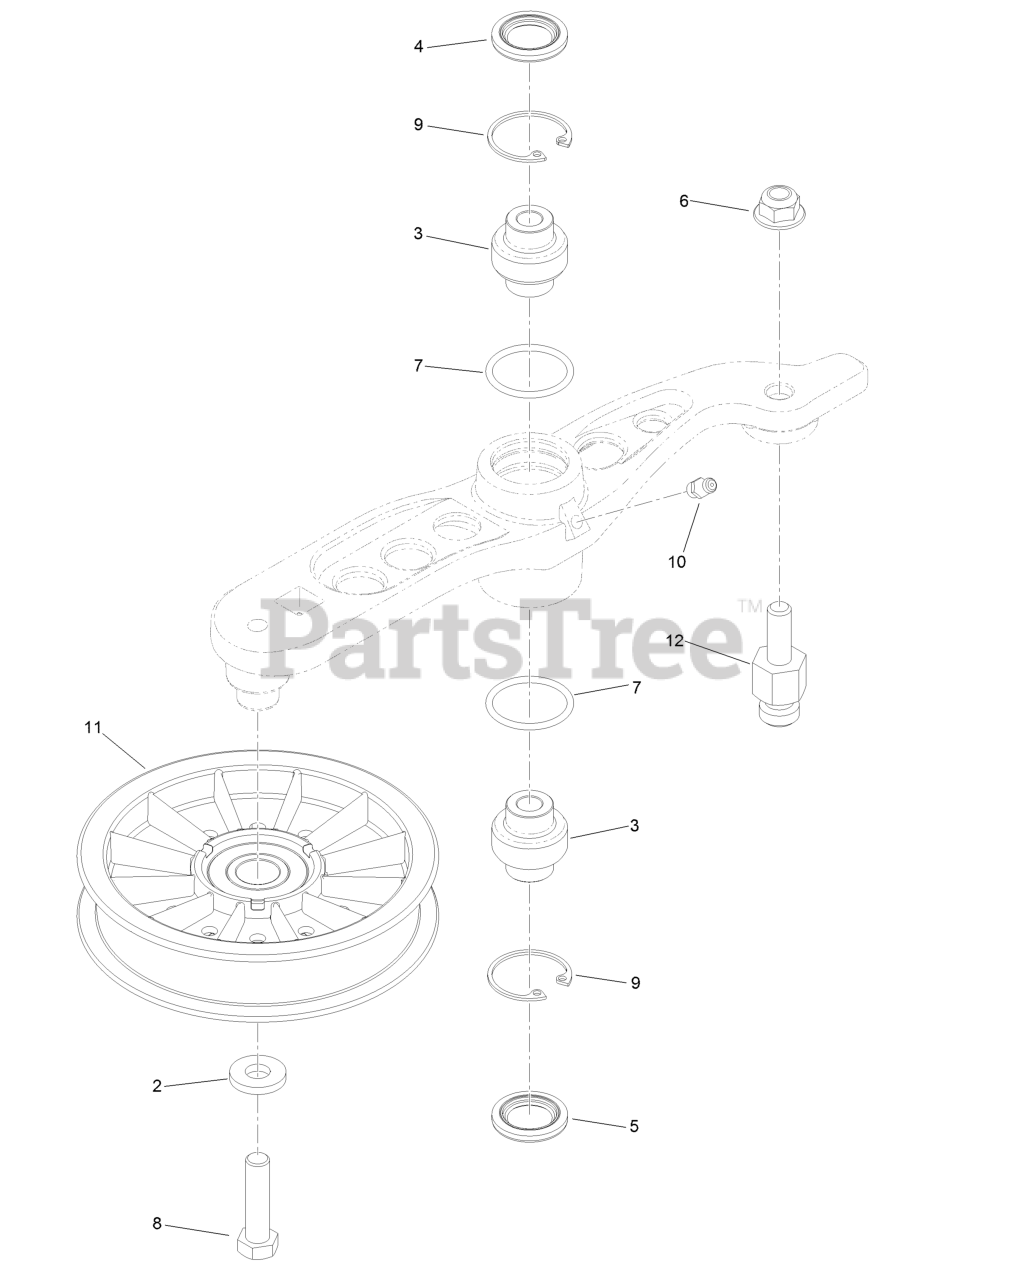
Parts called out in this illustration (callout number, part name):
3	Bearing-Spherical
4	Seal-Lip, Double
5	Seal-Single Lip
6	Nut-Nyloc 3/8-16 Flg
8	Screw-HH 3/8-16 X 1 1/2
9	Ring-Retaining
10	Zerk-1/4-28 Str
11	Pulley-Idler
12	Pin-Anchor, Spring
